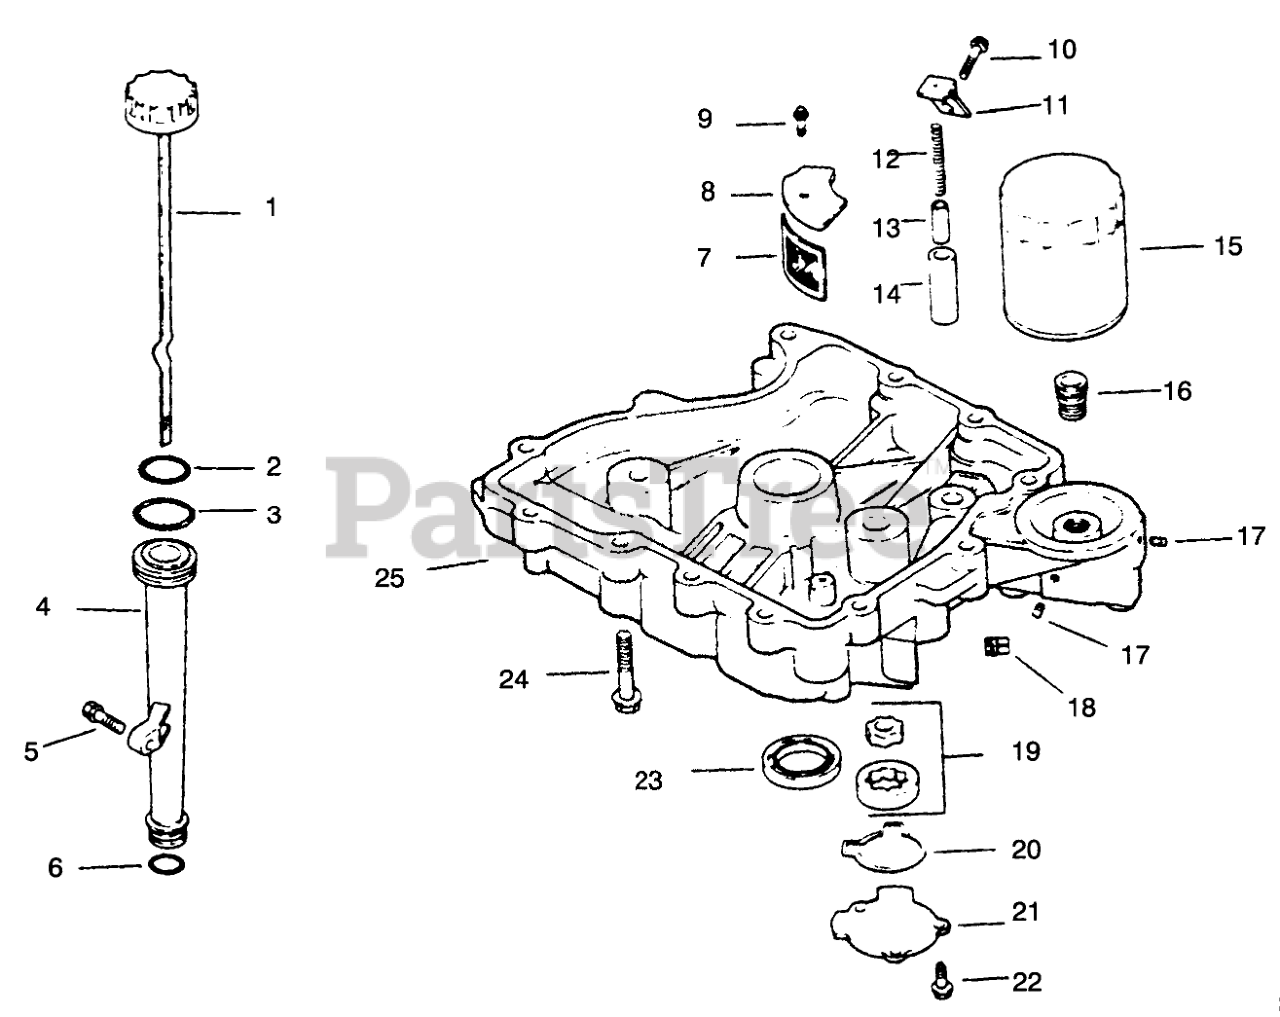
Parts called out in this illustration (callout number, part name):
1	Dipstick INC 2-3
2	"O"Ring
3	"O"Ring
4	Tube-Oil Fill
5	Screw
6	"O"Ring
7	Screen-Oil Pickup
8	Cover-Oil Screen
9	Screw
10	Screw
11	Bracket-Oil Pump Relief
12	Spring-Oil Relief Valve
13	Piston-Oil Relief Valve
14	Body-Oil Relief Valve
15	Filter-Oil
16	Adapter-Oil Filter
17	Plug-SH 1/8
18	Plug
19	Pump-Oil
20	"O"Ring-Pump Cover
21	Cover-Oil Pump
22	Screw
23	Seal-Crankshaft
25	Pan-Oil
